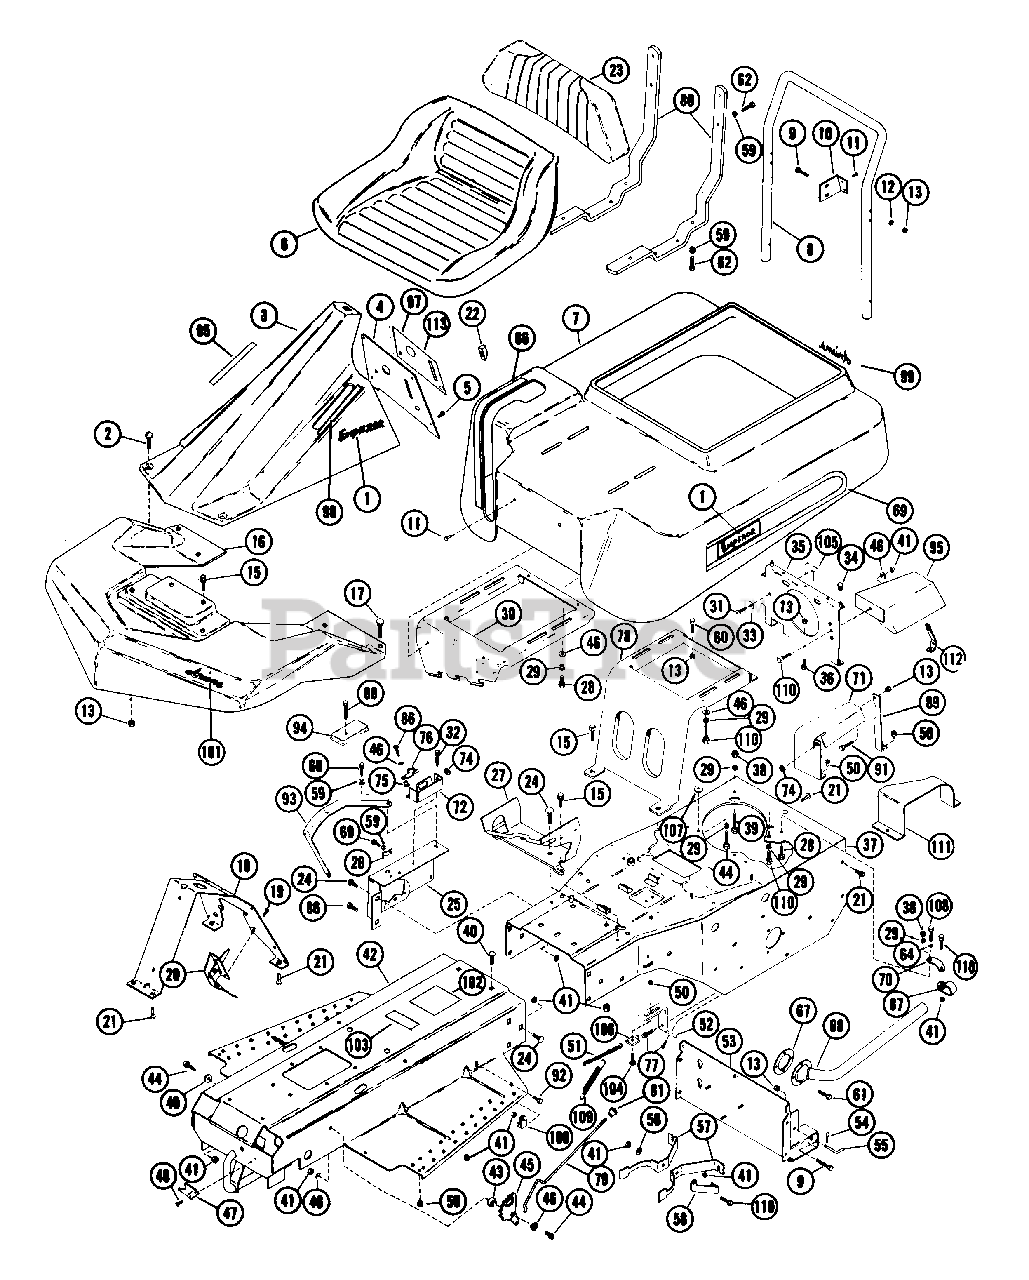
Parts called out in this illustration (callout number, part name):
1	EMPEROR NAME PLATE
2	SCR-MCH .25-20X.63 CRPH PL
4	DASH COVER ASSEMBLY
5	SCR-TAP 10-12X.50 CRPH PL A
6	SEAT
7	ENGINE COVER ASSEMBLY
8	SERVICE BAR
9	BLT-HEX .25-20X1.50 PL GR5
10	BRACKET
11	RVT-POP .187X.402 DOME ST
12	WSHR-FL-STL.312X.734X.065PL
13	NUT-LK-CTR .250-20 PL
15	BLT-SERHFWH .25-20X.50 PL
16	FRONT WHEEL COVERS
17	SCR-SLTR-SERNK .25-20X.62 PL
18	CONTROL PANEL
19	SCR-TAP 10-24X.375 CRPH 1A
20	THROTTLE CONTROL
21	BLT-SERHFWH .31-18X.50 PL
23	SEAT BACK
24	BLT-RDHDSQSHNK .31-18X.50 YZ
25	SHIFT QUADRANT
26	CLIP
27	SEAT HINGE
28	BLT-HEX .31-18X1.50 PL GR2
29	WSHR-LK .312X.097 PL HVY
30	BRACKET
31	SCR-TAP 10-16X1.0 SLHP PL AB
32	SCR-TAP 10-24X.375 CRPH 1A
33	WSHR-FL-STL .250X.562X.049 PL
34	BUMPER GROMMET
36	BLT-HEX .25-20X.50 PL GR2
37	FRAME
38	NUT-HEX .312-18
39	BLT-HEX .31-18X1.25 PL GR2
40	BLT-RDHDSQNK .312-18X.62 PL
41	NUT-LK .312-18 GR A PL
42	FRONT FRAME ASSY.
43	SPACER -SHLD .344X.500X.469
44	BLT-HEX .31-18X1.00 PL GR 2
45	BRAKE LATCH
46	WSHR-FL-STL .38X.875X.083 PL
47	LOCK SPRING
48	SCR-TAP 10-12X.50 CRPH PL A
49	WSHR-FL-STL .323X.625X.062 PL
50	NUT-LK-FLG .250-20 PL
51	BRAKE CHAIN
52	BRACKET
54	PIN-HAIR INT .09X1.88 PL
55	PIN
56	WSHR-FL-STL .323X.625X.062 PL
57	BELT FINGER
58	BELT FINGER BRACE
59	WSHR-LK .250X.077 HVY PL
60	BLT-HEX .25-20X.50 PL GR2
61	SCR-TAP 8-32X.38 SL HWH PL 23
62	BLT-HEX .25-20X.75 PL GR2
64	WSHR-LK .375X.115 HVY PL
65	MOWER HEIGHT DECAL
66	SHIFT DECAL
67	GASKET
68	PIPE
68	EXHAUST PIPE
69	SHROUD DECAL
70	MUFFLER BRACKET
71	SHIELD
72	SWITCH HOUSING
74	GROMMET, .31 ID
75	BSHG, FLG .325X.499X.26X.88
76	CAM NO SCRAP
77	BLT-SERHFWH .25-20X.50 PL
78	SEAT BRACKET
79	PARKING BRAKE ROD
80	SEAT BRACE
86	BLT-SERHFWH .31-18X.75 PL
87	CLIP
88	SCR-TAP 12-14X1.25 CROVH PL 1A
89	BRACE
91	BLT-HEX .25-20X.38 PL GR2
92	BLT-HEX .31-18X.50 PL GR2
93	SHIFT PANEL
95	BAFFLE
97	DASH DECAL
98	MOWER CLUTCH DECAL
99	DECAL
101	ARIENS NAME PLATE
102	CAUTION DECAL
103	EMPEROR PATENT LABEL
104	BLT-RDHDSQNK .25-20X.62 PL
105	CLAMP
106	BRACKET
107	WSHR-FL-STL .328X.875X.062 PL
108	BLT-HEX .38-16X.75 PL GR2
109	SG-TENS .041X.35X2.11 WLD 8
110	BLT-HEX .31-18X.75 PL GR2
111	HEAT SHIELD
112	CABLE BRACKET
113	DASH DECAL
113	6HP ENGINE DECAL
113	ENGINE LABEL
113	8 H P ENGINE DECAL
